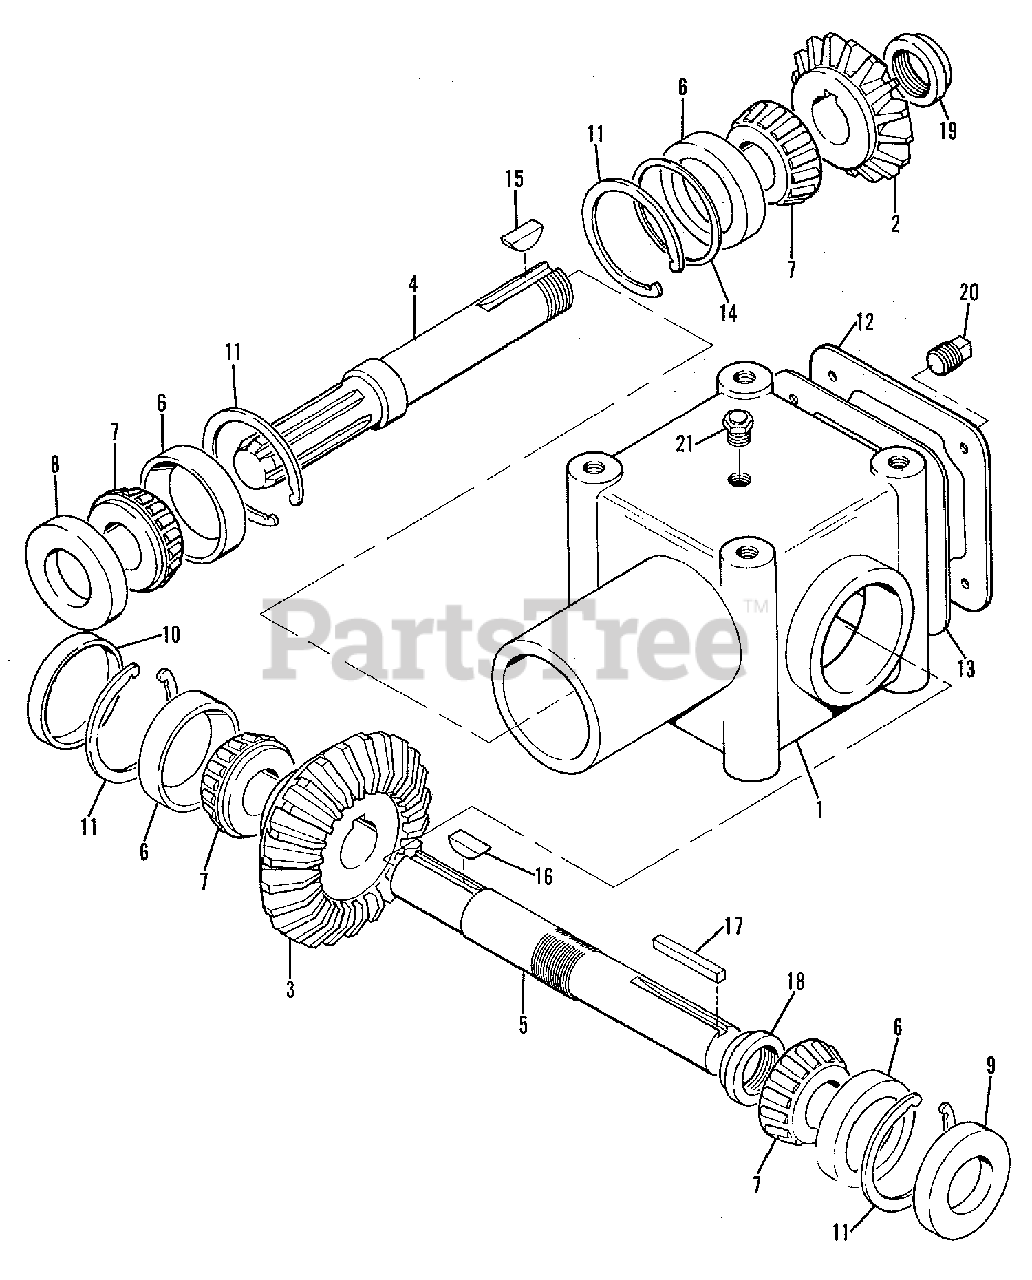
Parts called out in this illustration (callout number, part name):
1	GEARBOX ASSEMBLY
2	GEAR, Pinion (16T)
3	GEAR, Pinion (24T)
4	SHAFT, Input (w/Splines)
5	SHAFT, Output
6	CUP, Bearing
7	CONE, Bearing
8	SEAL, Oil, Input Shaft
9	SEAL, Oil, Output Shaft
11	RING, Retaining
12	PLATE, Cover
12	CAPSCREW, 5/16NC x 5/8
13	GASKET, Cover
15	KEY, Input Shaft
16	KEY, Output Shaft
17	KEY, Output Shaft, 3/8 Square x 2" Lg.
18	NUT, Stake, Output Shaft
19	NUT, Stake, Input Shaft
20	PLUG, Level
